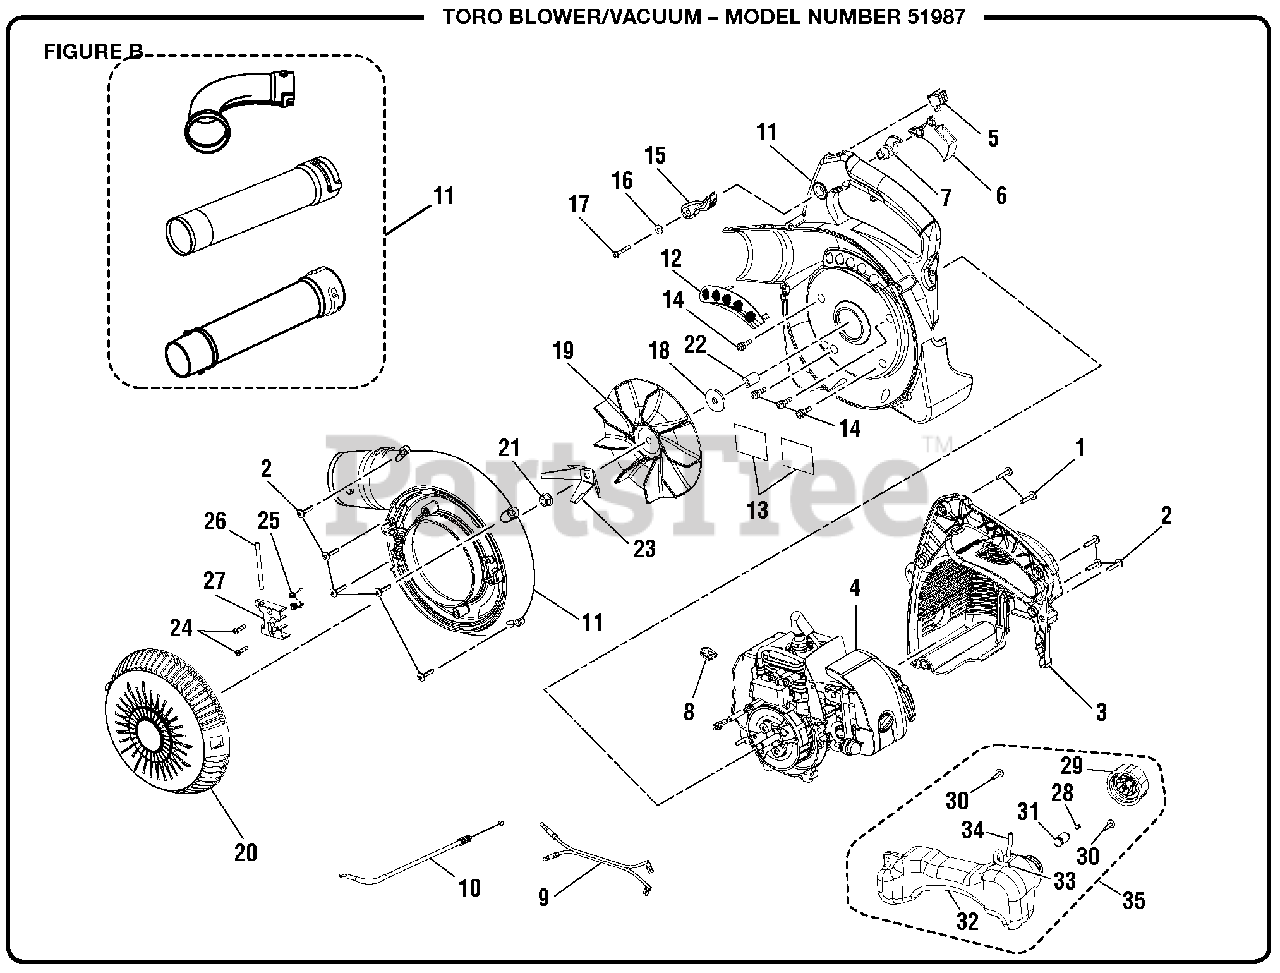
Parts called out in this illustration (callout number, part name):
2	Screw (10-14 x 7/8 in.)
3	Engine Shroud
5	Engine Switch
6	Throttle Trigger
7	Throttle Lock (Cruise Control)
8	Rubber Grommet
9	Wire Harness
10	Throttle Cable Assembly
11	Housing and Tube Assembly Kit
12	Mesh Screen
13	Heat Shield Tape
14	Screw (M5 x 20 mm)
15	Cruise Control Lever
16	Washer (Steel)
17	Screw (8-14 x 1 in.)
20	Vacuum Door
21	Lock Nut (M8 x 1.25)
23	Mulcher Blade
24	Screw (8-14 x 5/8 in.)
25	Hinge Spring
27	Vacuum Door Hinge
28	Filter Spring Clamp
29	Fuel Cap Assembly
30	Screw (10-14 x 7/8 in.)
31	Fuel Filter
32	Fuel Tank Assembly
33	Rubber Tubing (214 mm, Low Permeation)
34	Rubber Tubing (114 mm, Low Permeation)
35	Fuel Tank and Cap Assembly
